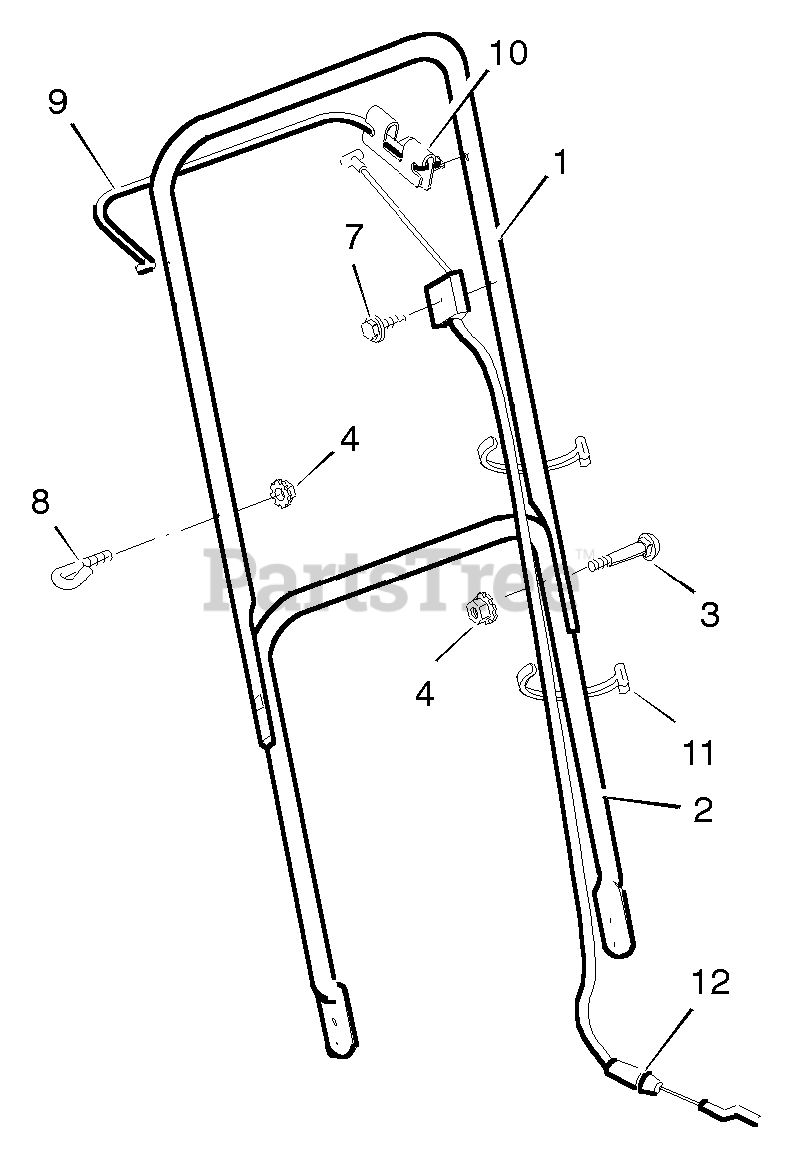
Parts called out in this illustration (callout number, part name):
1	Handle, Upper - Straight
2	Handle, Lower
4	Locknut
8	GUIDE, ROPE
9	Engine Stop Lever - Straight
10	Bracket, Stop Lever
11	Fastener, Cable
12	Engine Stop Cable
